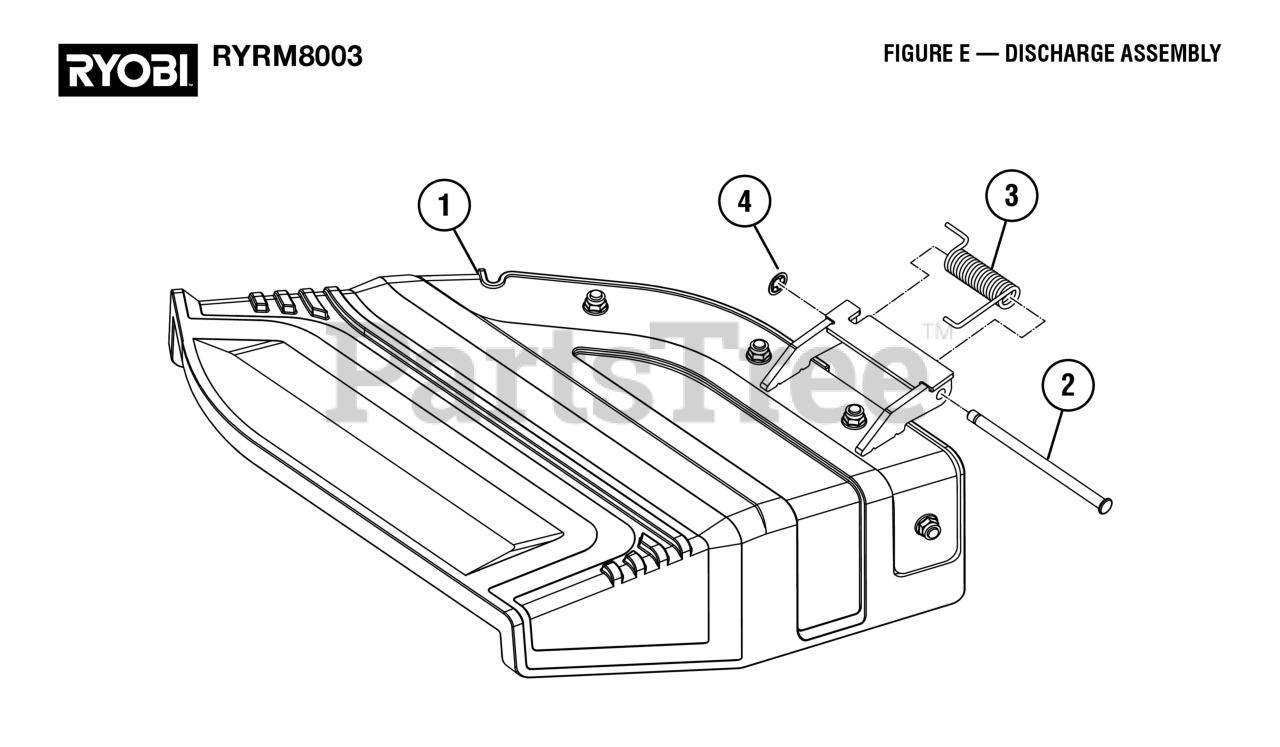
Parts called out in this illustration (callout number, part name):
1	Side Discharge Chute Assembly
2	Discharge Chute Hinge
3	Torsion Spring (19 x 62 x 3.02t)
4	Retainer Clip
